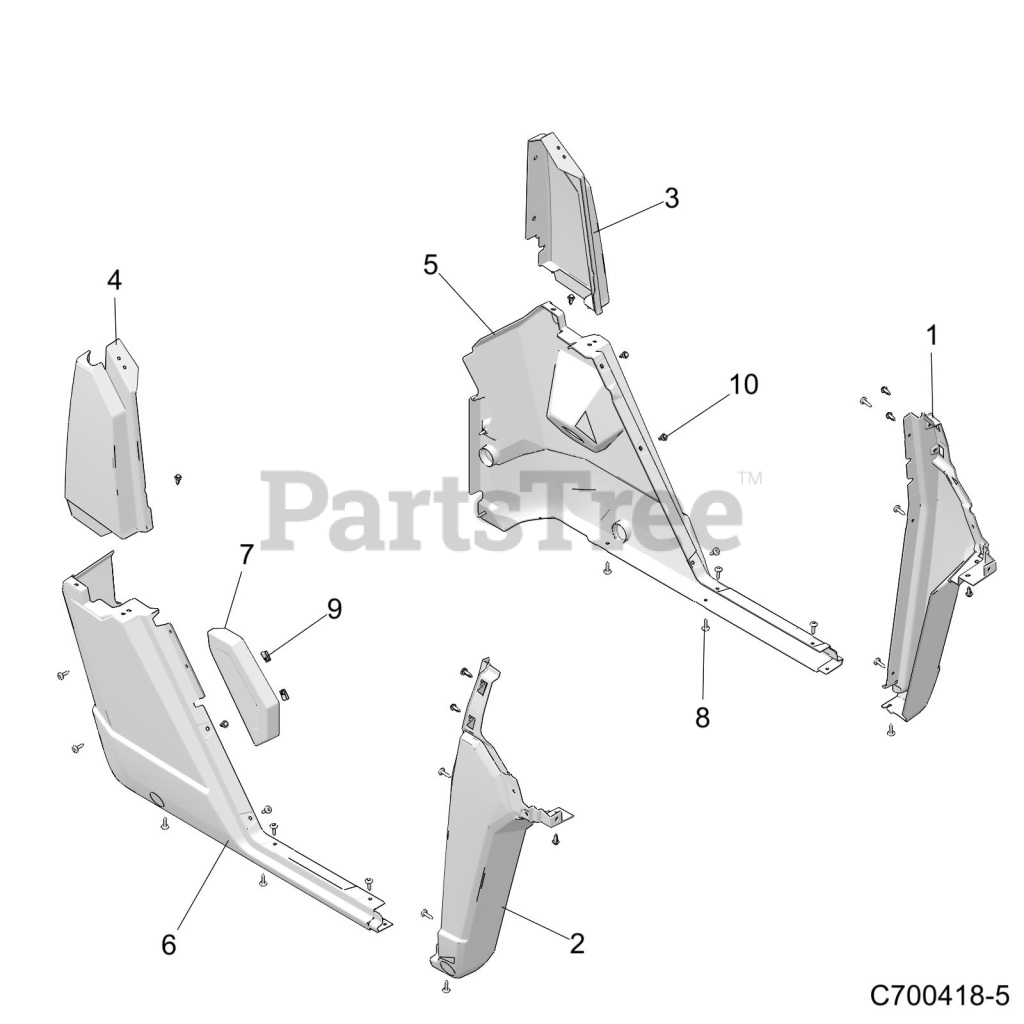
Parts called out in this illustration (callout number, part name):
1	COVER,FRONT,LH,BLK
2	COVER,FRONT,RH,BLK
3	FENDER-REAR,UPPER,LH,BLK
4	FENDER-REAR,UPPER,RH,BLK
5	COVER-ROCKER,LH,BLK
6	COVER-ROCKER,RH,BLK
7	COVER-SEAT PIVOT,BLK
8	SCR-TXTH-M6X1.0X25 RIE
9	NUT-M6-1.0,U-TYPE (2.5-3.8)
10	RIVET-TUFLOK,.315-.325X.787 (5
